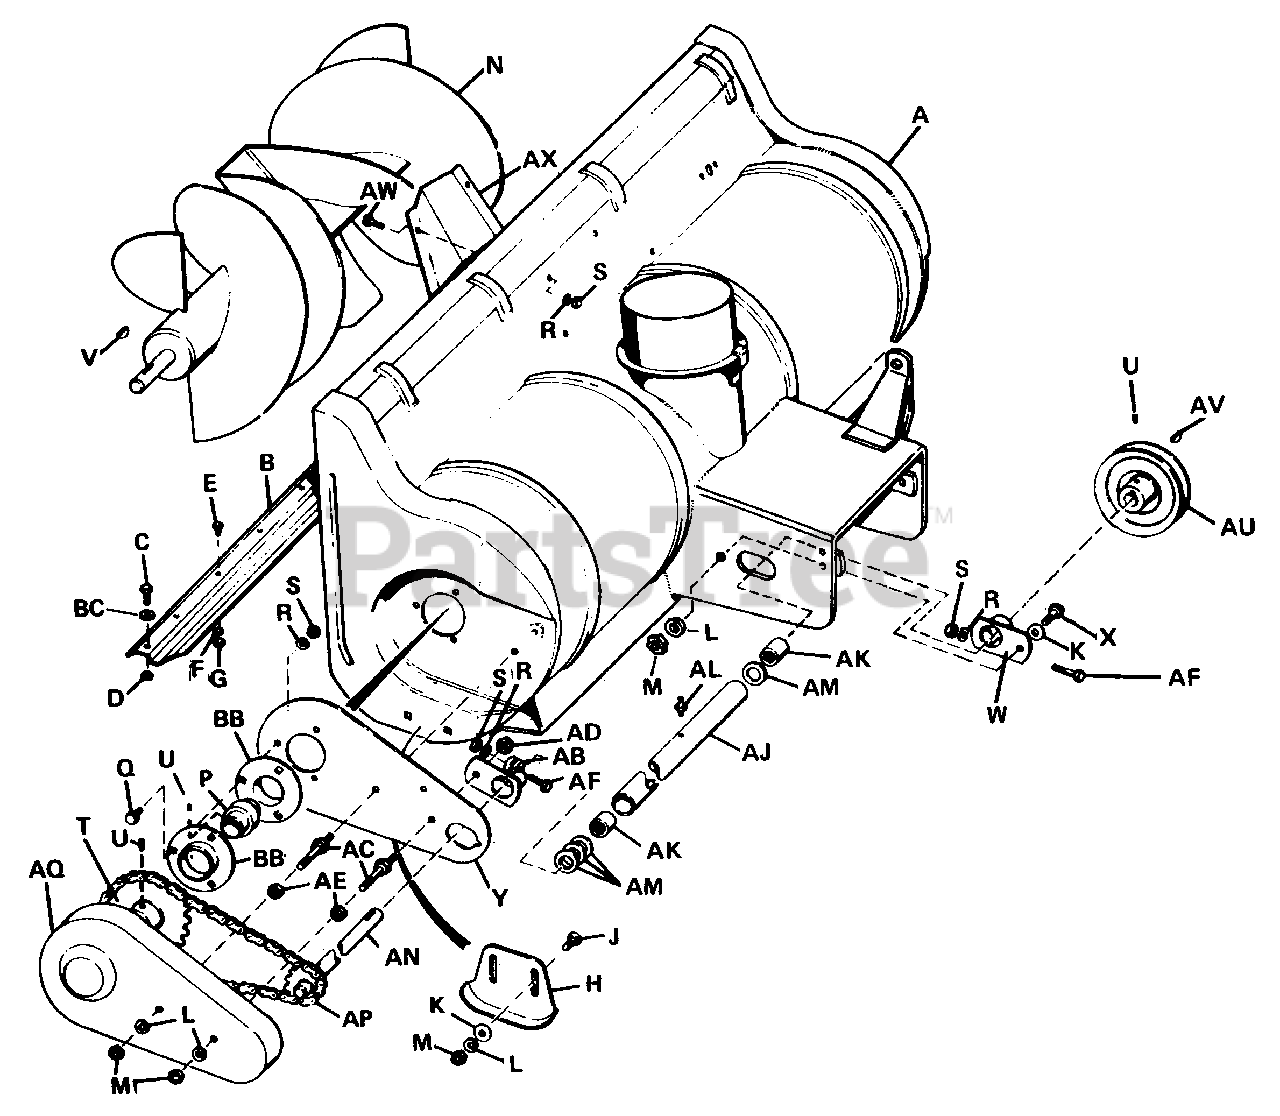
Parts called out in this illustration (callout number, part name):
A	Body Assembly
B	Body Scraper
C	Hex. Cap Screw, 5/16"-18 x 5/8"
D	Full Lock Hex. Nut, 5/16"-18
E	Hex. Cap Screw, 1/4"-20 x 5/8"
F	Lock Washer, 1/4"
G	Full Hex. Nut, 1/4"-20
J	Carriage Bolt, 3/8"-16 x 3/4"
K	Plain Washer, 3/8"
L	Lock Washer, 3/8"
M	Full Hex. Nut, 3/8"-16
N	Rotor Assembly
P	Bearing Cartridge w/713509 Set Screw
Q	Hex. Cap Screw, 5/16"-18 x 3/4"
R	Lock Washer, 5/16"
S	Full Hex. Nut, 5/16"-18
T	Rotor Sprocket
U	Set Screw, 5/16"-18 x 5/16"
W	Support Assembly Clamp
X	Hex. Cap Screw, 3/8"-1 x 1"
Y	Side Plate
AB	Support Assembly Clamp
AD	Nut, Flange, 3/8"-16
AE	Full Lock Hex. Nut, 3/8"-16
AF	Hex. Cap Screw, 5/16"-18 x 1-1/2"
AJ	Bearing Housing
AK	Needle Bearing
AL	Grease Fitting
AN	Shaft Assembly
AQ	Chain Guard
AV	Key, 3/16" Dia. x 3/4"
AW	Hex. Cap Screw, 5/6"-18 x 5/8"
BB	Bearing Flange
